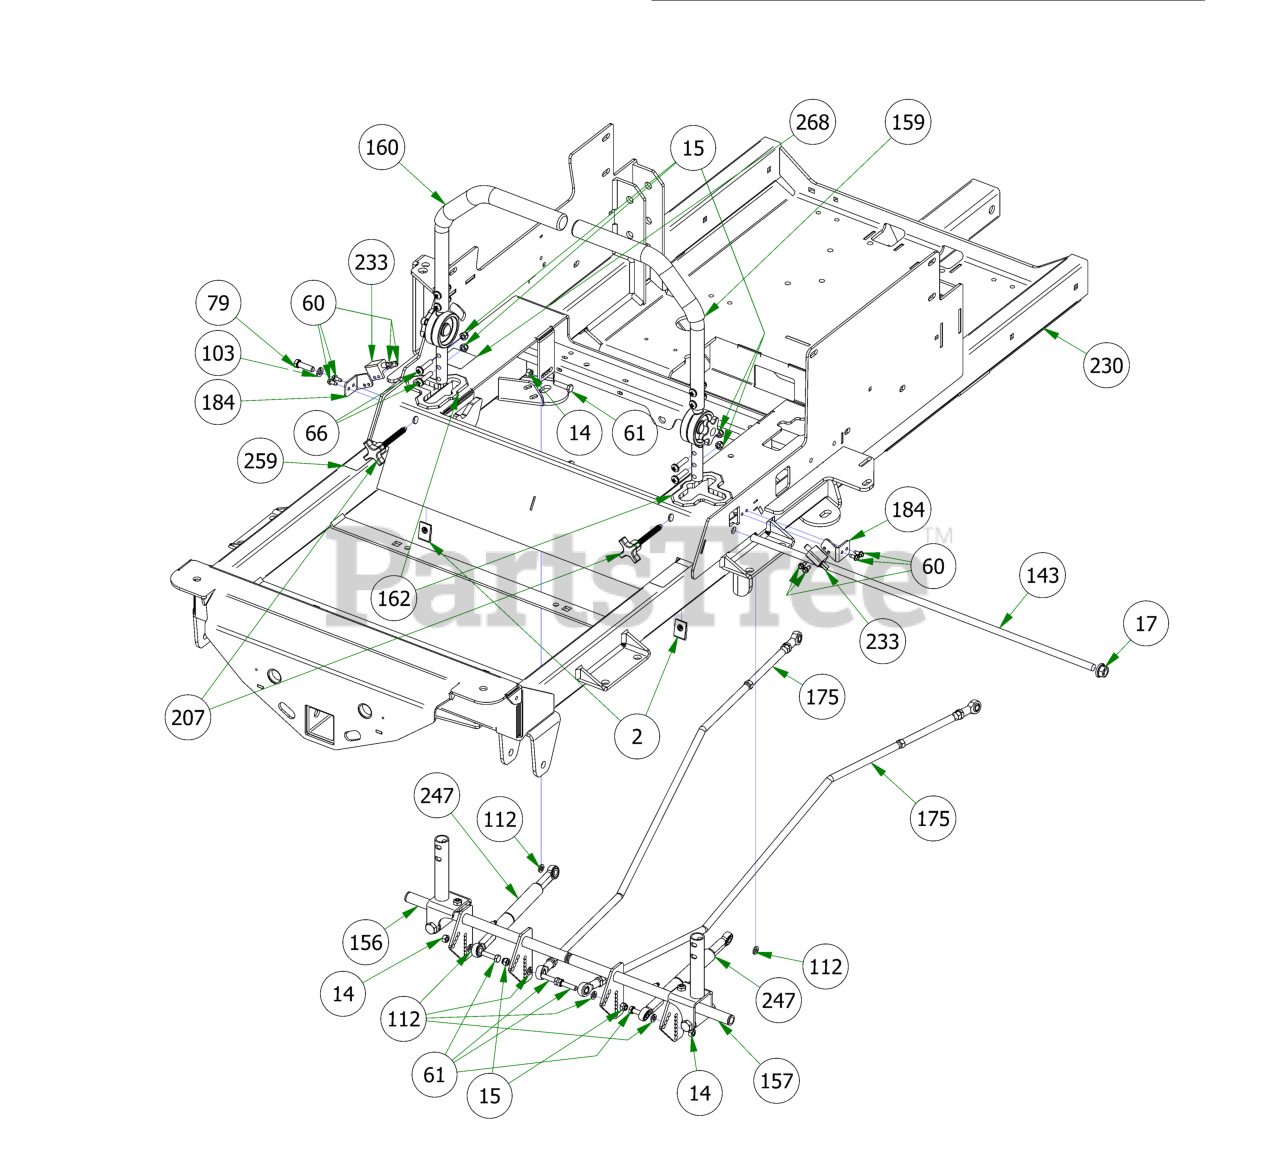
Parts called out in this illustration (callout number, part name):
2	Extruded Nut 3/8"-16 3/4" Hole Center With Patch
14	5/16-18 HEX NUT ZINC
15	5/16-18 NYL INS L/N ZC
17	1/2-13 NYLON INSERT FLANGE LOCKNUT ZINC
60	12-24 X 1/2 HEX WASHER UNLSOT F TCS ZINC
61	5/16-18 X 1-1/4 HEX C/S (GR.5) ZC
66	5/16-18 x 1 3/8" Futton Head Torx Drive Bolt
79	3/8-16 X 1-1/4 HEX CAP SCREW (GR.5) ZINC
103	3/8 SPLIT LOCKWASHER ZINC
112	5/16 SPLIT LOCKWASHER ZINC
143	2019 Steering Actuator Rod
156	2019 R Series RH Arm Rod Assembly
157	2019 R Series LH Arm Rod Assembly
159	2019 Left Hand ADJ. Steering Arm Kit
160	2019 Right Hand ADJ. Steering Arm Kit
162	Snap-in Drive Arm Bushing
175	2019 Renegade Push Rod Assembly
184	2019 Arm Switch Bracket
207	Speed Limiting Knob 3/8-16X 3"
230	2019 Renegade Gas Frame - Powdercoated
233	Safety Switch
247	2019 SROID Damper With Spherical Rod Ends
259	2018 LH/RH Steering Control Decal Roll
268	2019 Deck Release Decal
